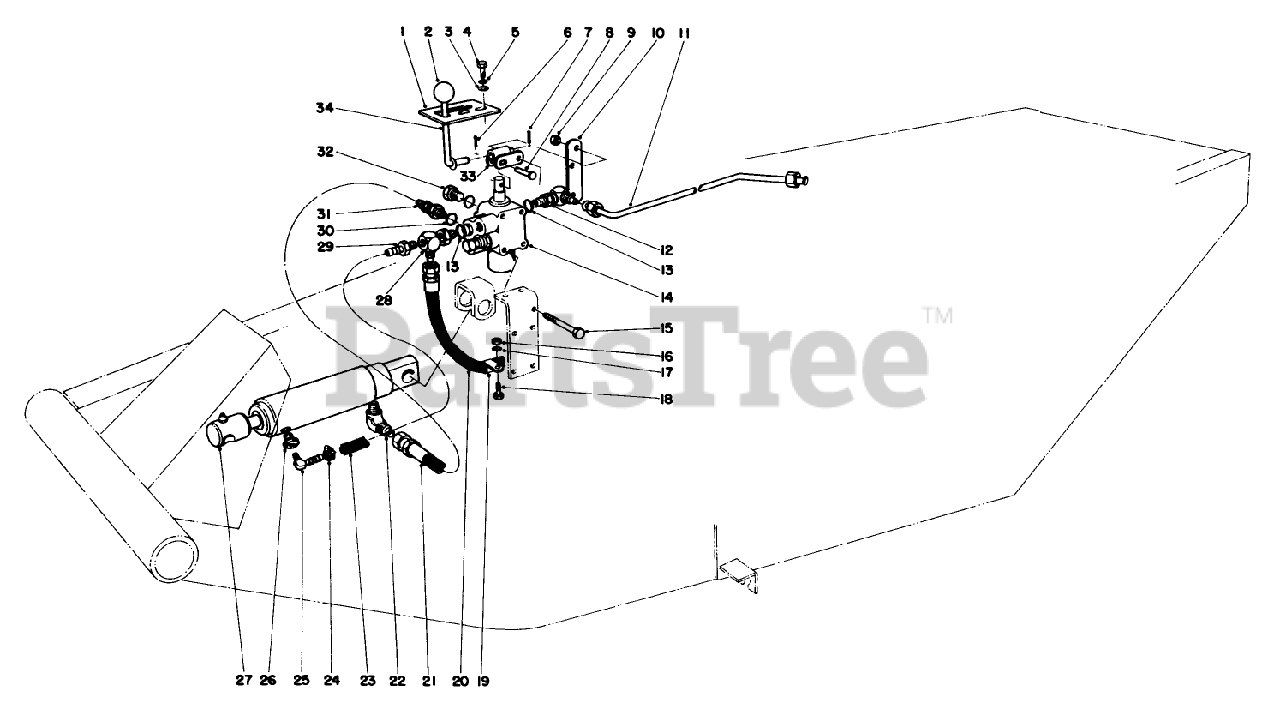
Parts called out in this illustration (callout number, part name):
1	LATCH-LEVER, VALVE
3	WASHER-FLAT
4	WASHER-LOCK
5	SCREW-HH
6	PIN-COTTER
7	PIN-ROLL
8	PIN-CLEVIS
9	NUT-LOCK, NI
10	LEVER-VALVE, PIVOT MOUNT
11	PRESSURE LINE TUBE
12	FITTING-ELBOW, 90 DEG
13	O-RING
14	Valve ASM
15	SCREW-HH
16	NUT-HEX
17	WASHER-LOCK
18	SCREW-HH
19	CLAMP-R
20	HOSE-VALVE TO COOLER
21	VALVE-CYLINDER HOSE
22	ELBOW
23	GAS LINE
24	CLAMP-HOSE
25	CONNECTOR-HOSE
26	REDUCING BSGH
27	Hydraulic Cylinder
28	FITTING ASM
29	FITTING-STRAIGHT
30	O-RING
31	FITTING-ELBOW, 90
33	Link-Valve Lever
34	Lever Valve
